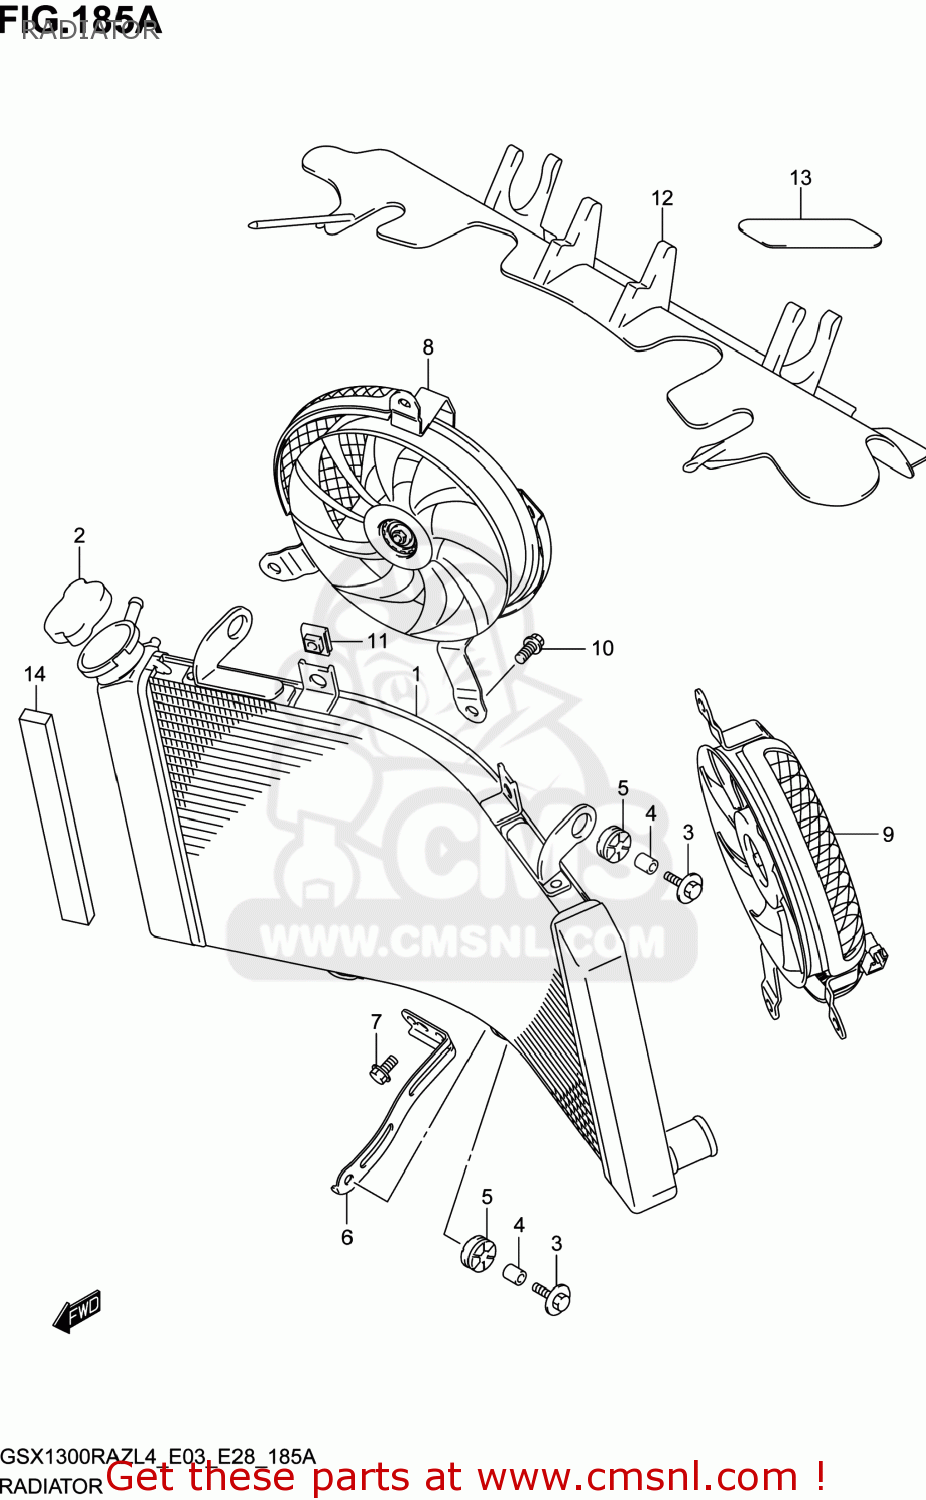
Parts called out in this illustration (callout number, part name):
1	RADIATOR ASSY,
2	CAP,RADIATOR
3	BOLT(6X25)
4	SPACER(6.5X10X12)
5	CUSHION
6	BRACKET,RADIATOR
7	BOLT
8	FAN ASSY,RADIATOR,R
9	FAN ASSY,RADIATOR,L
10	BOLT,FAN ASSY
11	NUT,FAN ASSY
12	SHIELD,RADIATOR HEAT
13	TAPE,RR FENDER
14	CUSHION,UNDER COWLING
